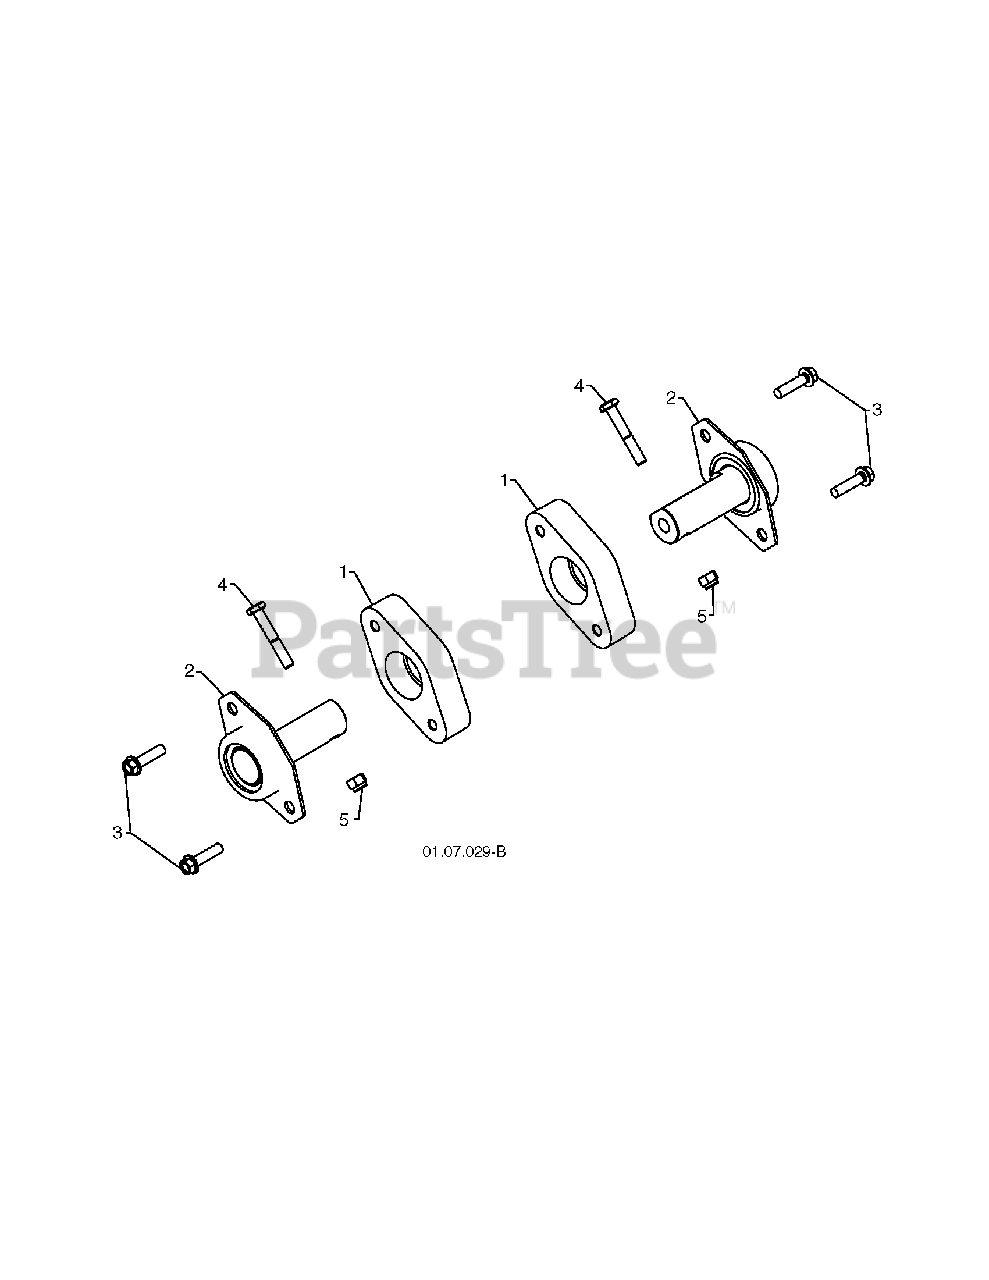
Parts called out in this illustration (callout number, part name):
1	BEARING RETAINER, PLASTIC
2	BEARING.BALL.AUGER.FLAT.
3	SCREW, HEX HD 5/16X1
4	SCREW.HEX.HD1/4-20X
5	LOCKNUT.NYLOC.1/4-20
